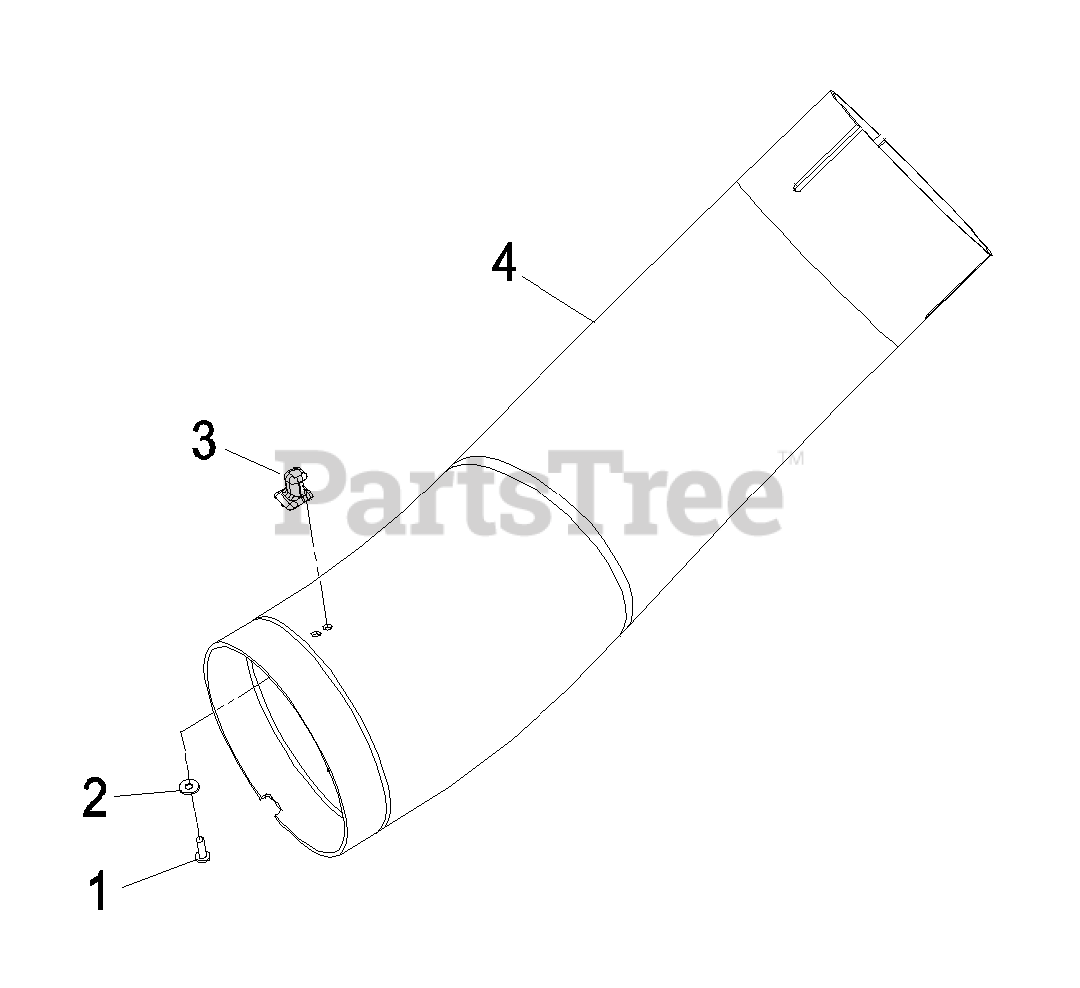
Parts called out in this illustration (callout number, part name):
1	SCREW-PPH
2	WASHER-FLAT
3	LATCH-KEEPER
4	KIT,LOWER TUBE
